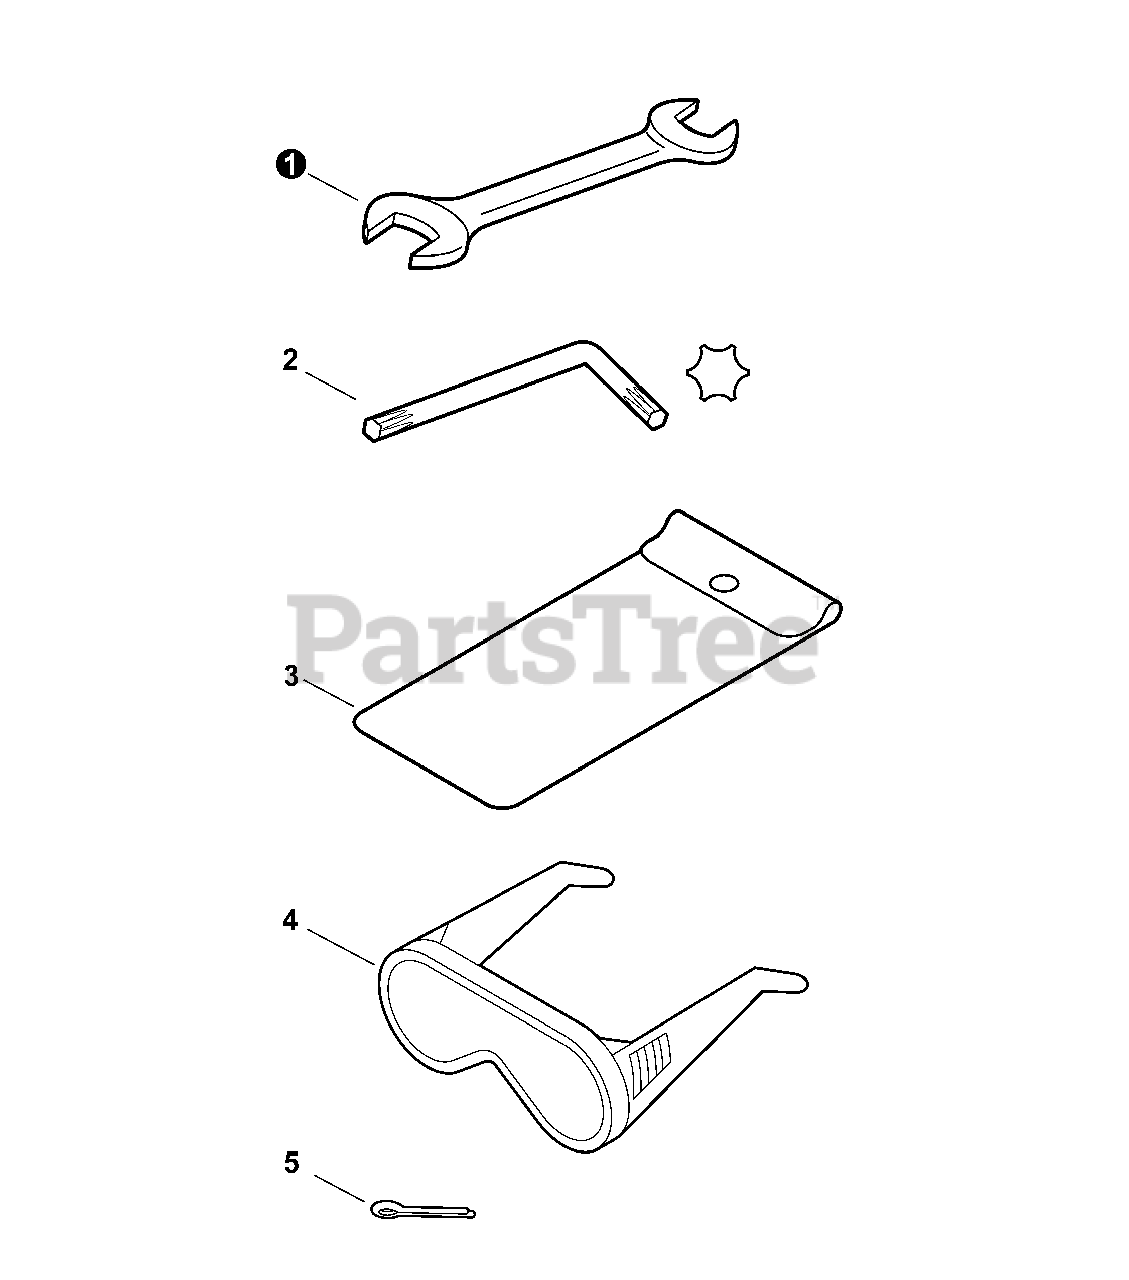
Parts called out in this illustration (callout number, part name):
1	SPANNER - 8×10mm
2	TORX KEY - T27
3	TOOL BAG
4	GOGGLES
5	PIN, SPLIT 2×22
